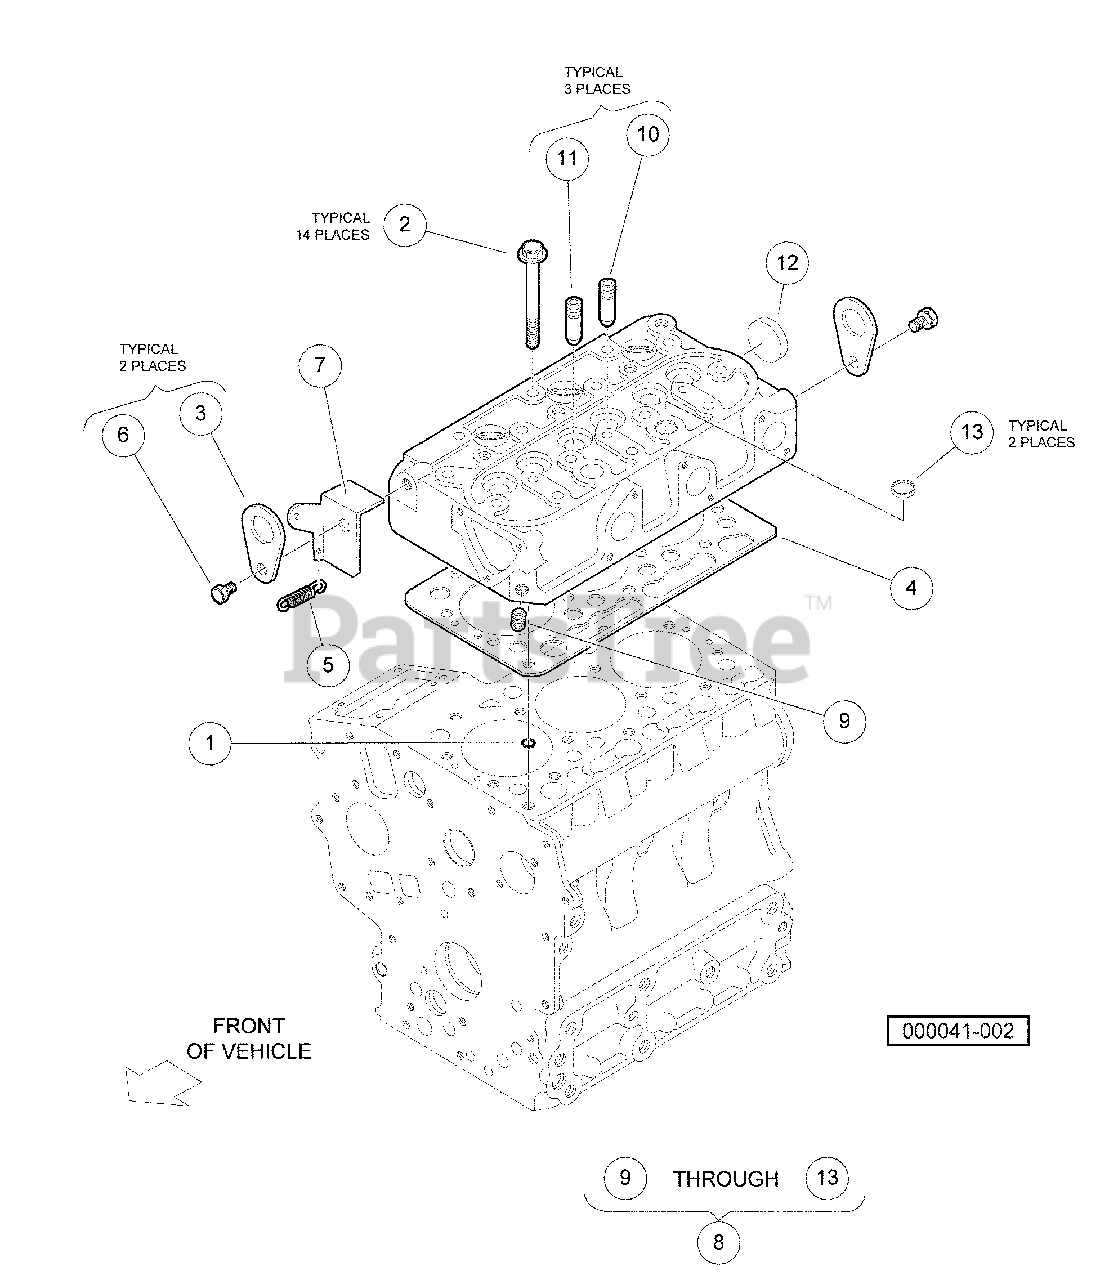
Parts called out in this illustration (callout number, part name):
1	O Ring, 8 X 7
2	Bolt, Cylinder Head
3	Hook, Engine
4	Gasket, Cylinder Head
5	Spring, Start
6	Bolt, Engine Hook
7	Stay, Cylinder Head
8	Head, Cylinder, Complete
9	Plug, 3/32"
10	Guide, Exhaust Valve
11	Guide, Inlet Valve
12	Cap, Sealing, Head
13	Cap, Sealing, Head, Top
